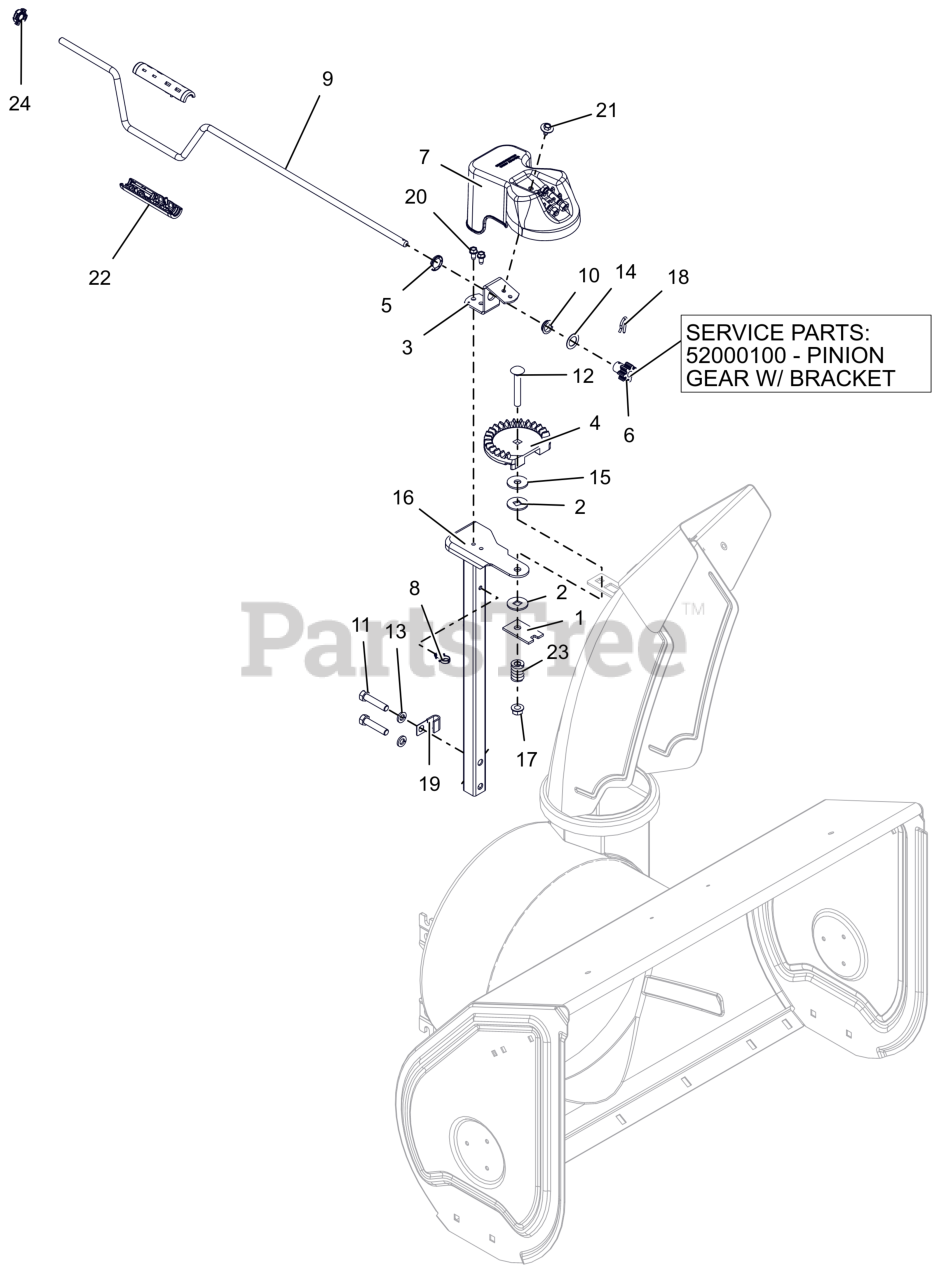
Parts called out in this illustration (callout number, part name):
1	PLATE, FRICTION
2	FRICTION WASHER
3	BRACKET, PINION GEAR
4	CHUTE GEAR
5	PUSHNUT .625
6	PINION GEAR - CHUTE
6	PINION GEAR W/BRACKET
7	GEAR COVER ASSY LG SHEAR BOLT
8	CLIP, CABLE GUIDE
9	ROD, CHUTE CRANK
10	BUSHING, POLYLINER-.63 SNAPIN
11	BLT, HEX .38-16X1.75 G5 ZCC
12	BLT,RHSN .38-16X2.50 G5 ZCC
13	WSHR,LK-REG .375X.094 ZCC
14	WSHR-THRST .625 X 1.0 X .03
15	WSHR FL STL .406X1.25X.10ZC120
16	PEDESTAL, CHUTE - CRANK
17	NUT-LK-TOP-FLG .38-16 ZC120
18	PIN, SPRING CLIP
19	J-CLAMP
20	SCR-TAP .25-20X.50 HWH ZCC
21	SCR, TAP .25-20X.50 LG HWH ZCC
22	KNOB,CHUTE CRANK-DELUXE
23	SG-COMP .187X.56X1.62
24	CRANK BUSHING, NYLON CHUTE BK
